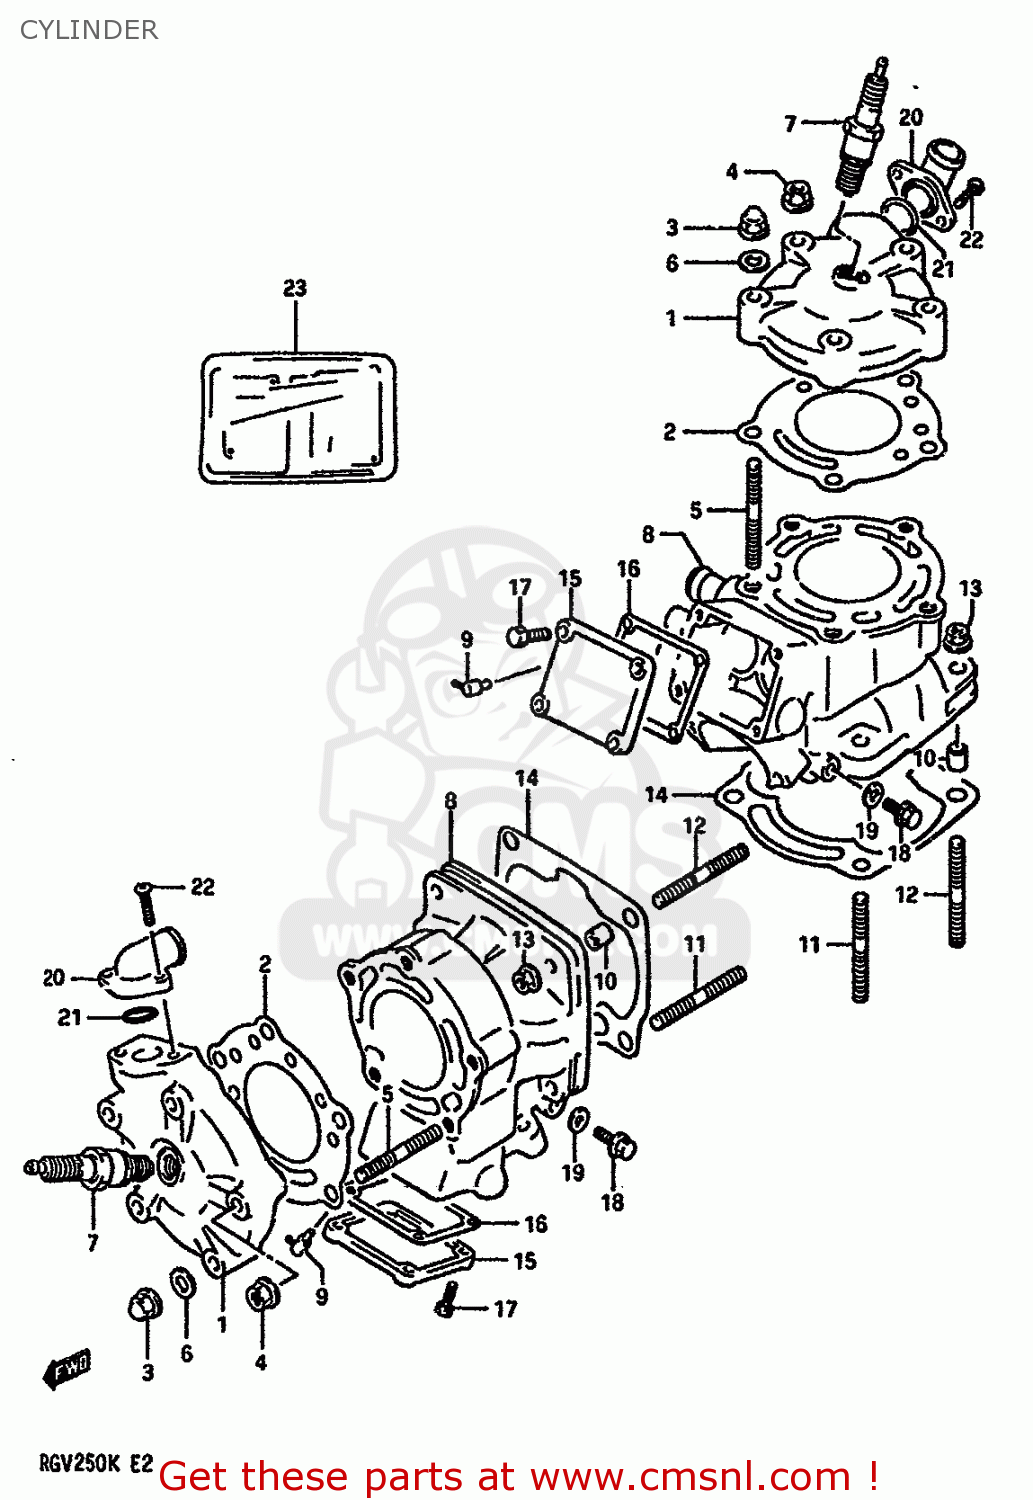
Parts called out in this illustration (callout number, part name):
1	HEAD,CYLINDER
2	GASKET,CYLINDER HEAD
3	NUT 8MM
4	NUT
5	BOLT,STUD
6	GASKET(8.5X17X2.3) (NAS)
7	PLUG,SPARK(BR9ES)
8	CYLINDER
9	VALVE,OIL HOSE CHECK
10	PIN
11	BOLT,STUD
12	STUD BOLT
13	NUT
14	GASKET,CYLINDER
15	COVER,CYLINDER
16	GASKET,CYLINDER COVER (MCA)
17	BOLT
18	BOLT
19	GASKET(6.2X13X1.2) (NAS)
20	CONNECTOR,WATER HOSE
21	O RING(D:1.9,ID:19.8)
22	SCREW
23	GASKET SET
